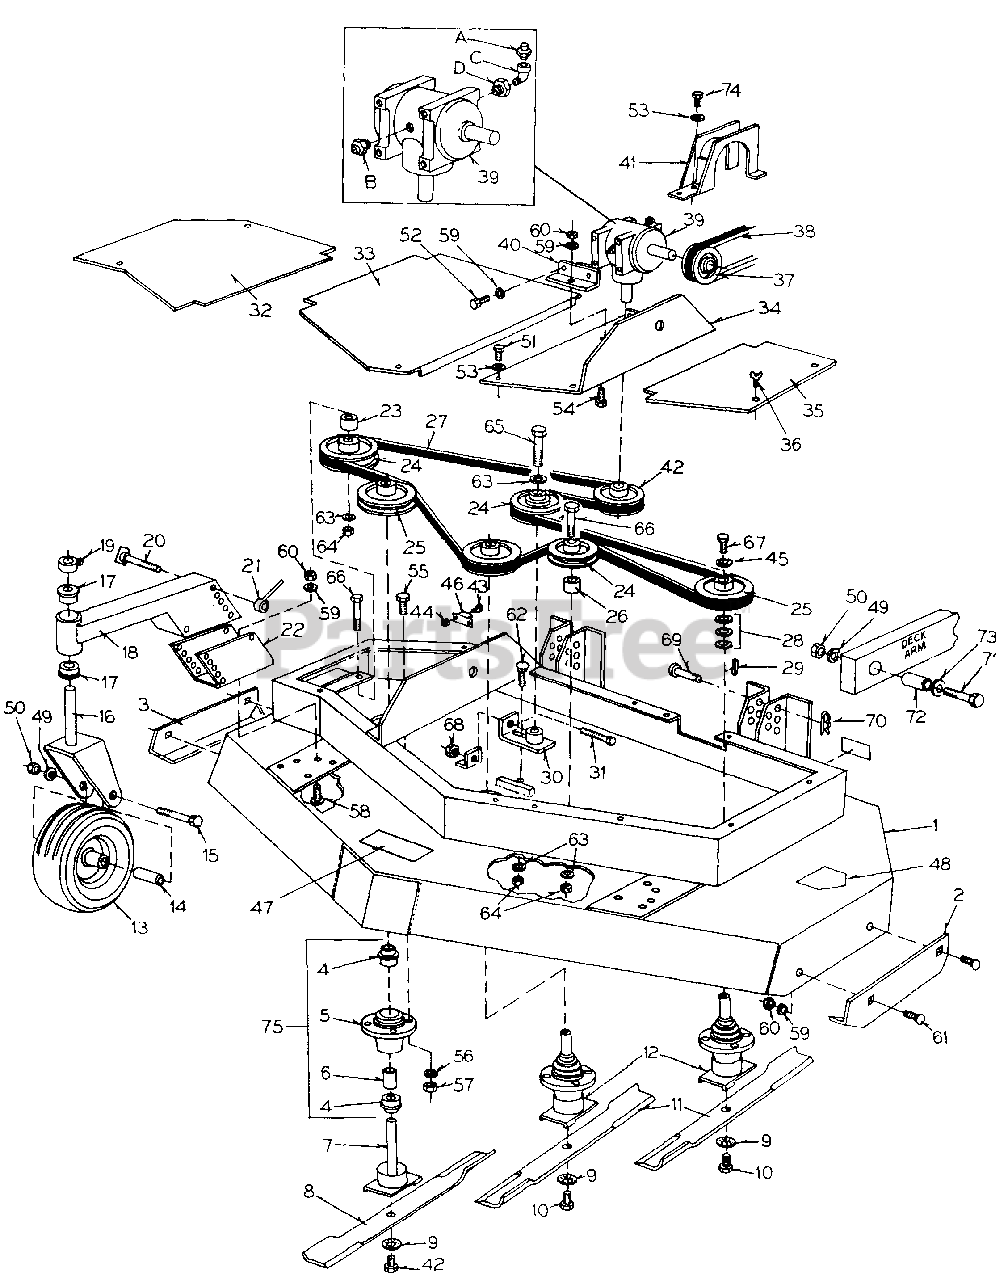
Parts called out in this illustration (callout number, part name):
1	Rear Discharge Deck, 52"
4	Spindle Bearing, 7/8"
5	Spindle Housing
6	Spindle Spacer
7	Spindle Shaft, LH Rotation
8	Blade, LH Rotation
10	Hex Bolt, 3/8-24 x 1 1/4", GR5
11	Blade, RH Rotation
12	Spindle Shaft, 7/8"
13	Gauge Wheel Assembly
14	Axle
15	Hex Bolt, 1/2-13 x 6 1/2", GR2
16	Gauge Wheel Fork
17	Drive Wheel Bearing, 1"
18	Gauge Wheel Mount
19	Set Collar, 1"
20	Wing Bolt, 3/8-16 x 4 1/2"
21	Handle Nut, 3/8-16
22	Gauge Wheel Mount Bracket
23	Idler Pulley Spacer
24	Idler Pulley, 3/8" ID x 5" OD
25	Spindle Pulley, 7/8" ID x 4 1/2" OD
26	Idler Pulley Spacer
27	Deck Belt, BB129
29	Key, 3/16" x 3/16" x 1"
30	Belt Tightener
31	Hex Tap Bolt, 1/4-20 x 4"
36	Thumb Screw, 1/4-20 x 1/2"
37	Gearbox Pulley, 3/4 ID x 4 1/2 OD
38	Deck Drive Belt, B52
39	Gearbox
39	Gearbox Assembly
40	Gearbox Mount Angle
42	Hex Bolt, 3/8-24 x 1 1/4", GR5, LH
44	Integral Star Washer Nut, No. 10-32
45	Spindle Washer
46	10 Amp Circuit Breaker
47	Decal, Caution - Whirling Blade
67	Hex Capscrew, 5/16-24 x 3/4", GR5
69	Clevis Pin, 1/2" x 1 1/2"
70	Hairpin Cotter, .120 x 2 1/4"
72	Deck Lift Arm Bushing
75	Spindle Housing Assembly
B	Grease Zerk, 1/4" NPT
C	Street Elbow, 1/8" x 90°
